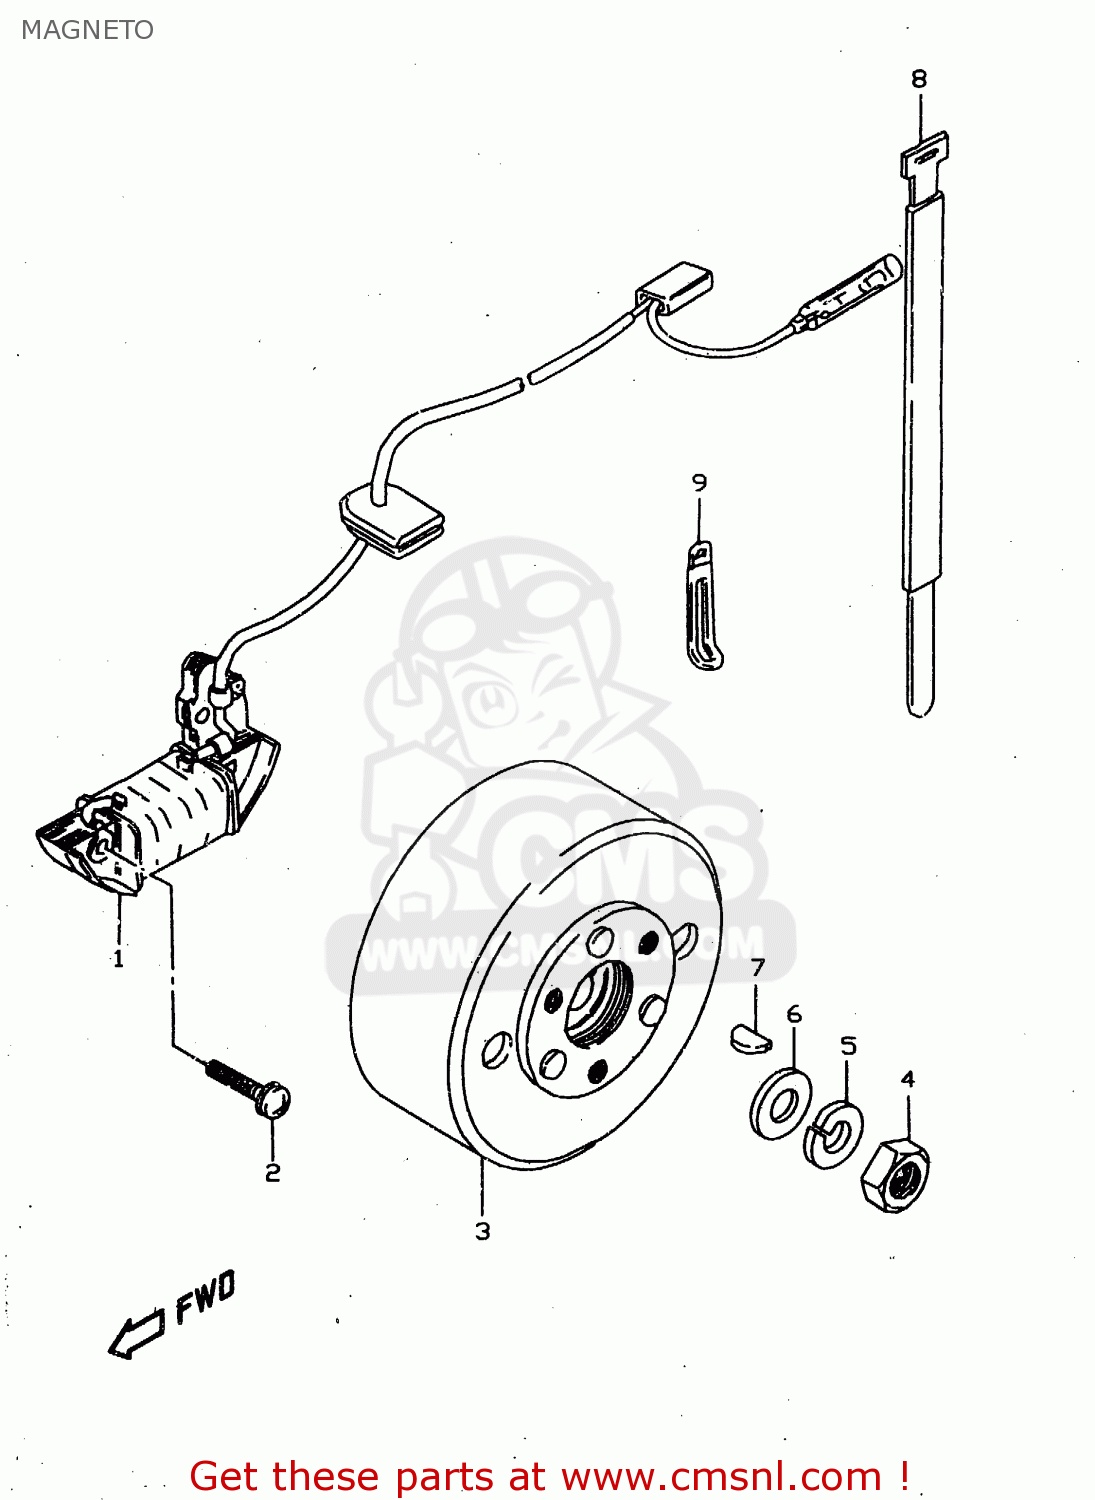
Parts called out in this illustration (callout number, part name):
1	COIL ASSY,IGNITION PRIMARY
2	SCREW
3	ROTOR ASSY
4	NUT
5	WASHER
6	WASHER
7	KEY
8	CLAMP
9	CLAMP(L:45)
